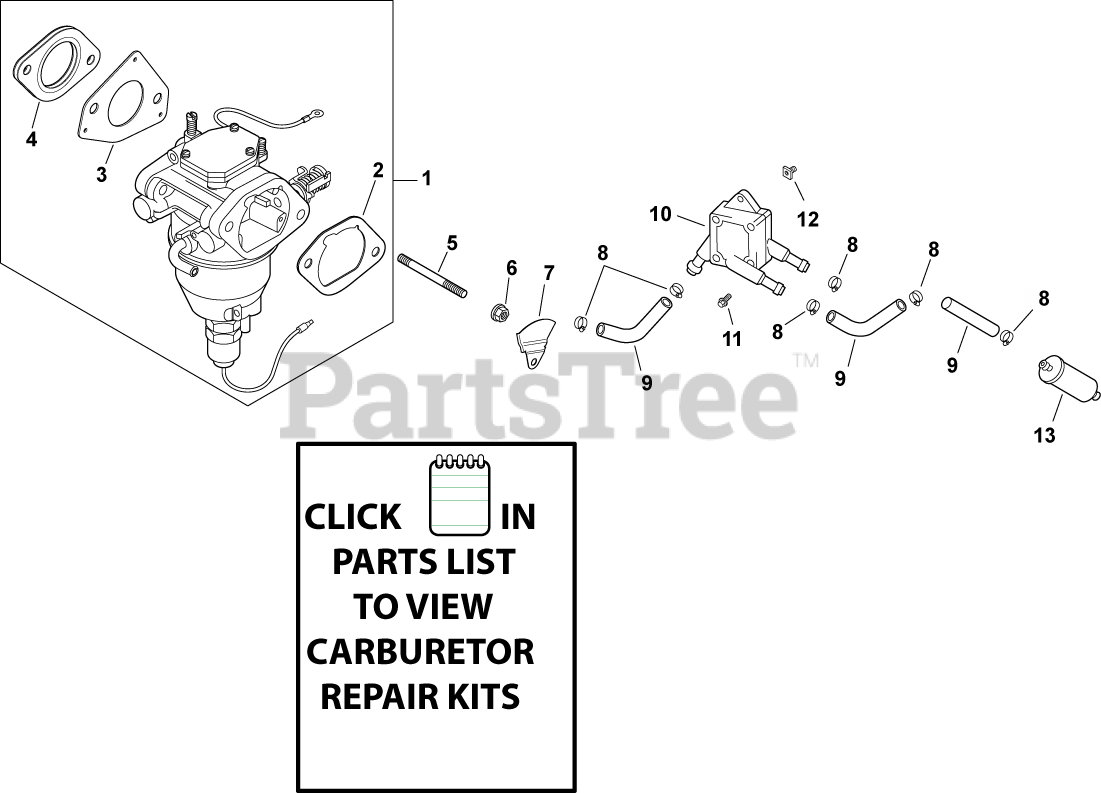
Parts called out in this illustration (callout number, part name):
1	CARBURETOR KIT-USE 24 853 169-S
2	GASKET, AIR CLEANER BASE
3	GASKET, CARBURETOR
4	GASKET, CARBURETOR
5	STUD,M6X1.0X96
6	NUT, FLG M6X1.0
7	BAFFLE, SPIT-BACK CUP-USE 24 063 105-S
8	CLAMP, HOSE (KM)-USE 25 237 31-S
9	HOSE,LW PERM.FUEL 24.00"-USE 25 111 81-S
10	PUMP, FUEL
11	SCREW, TAP M6X1.7X18
12	NUT, PLASTIC - BLACK
13	FILTER,FUEL 51 MICRON (FUEL PUMP)
